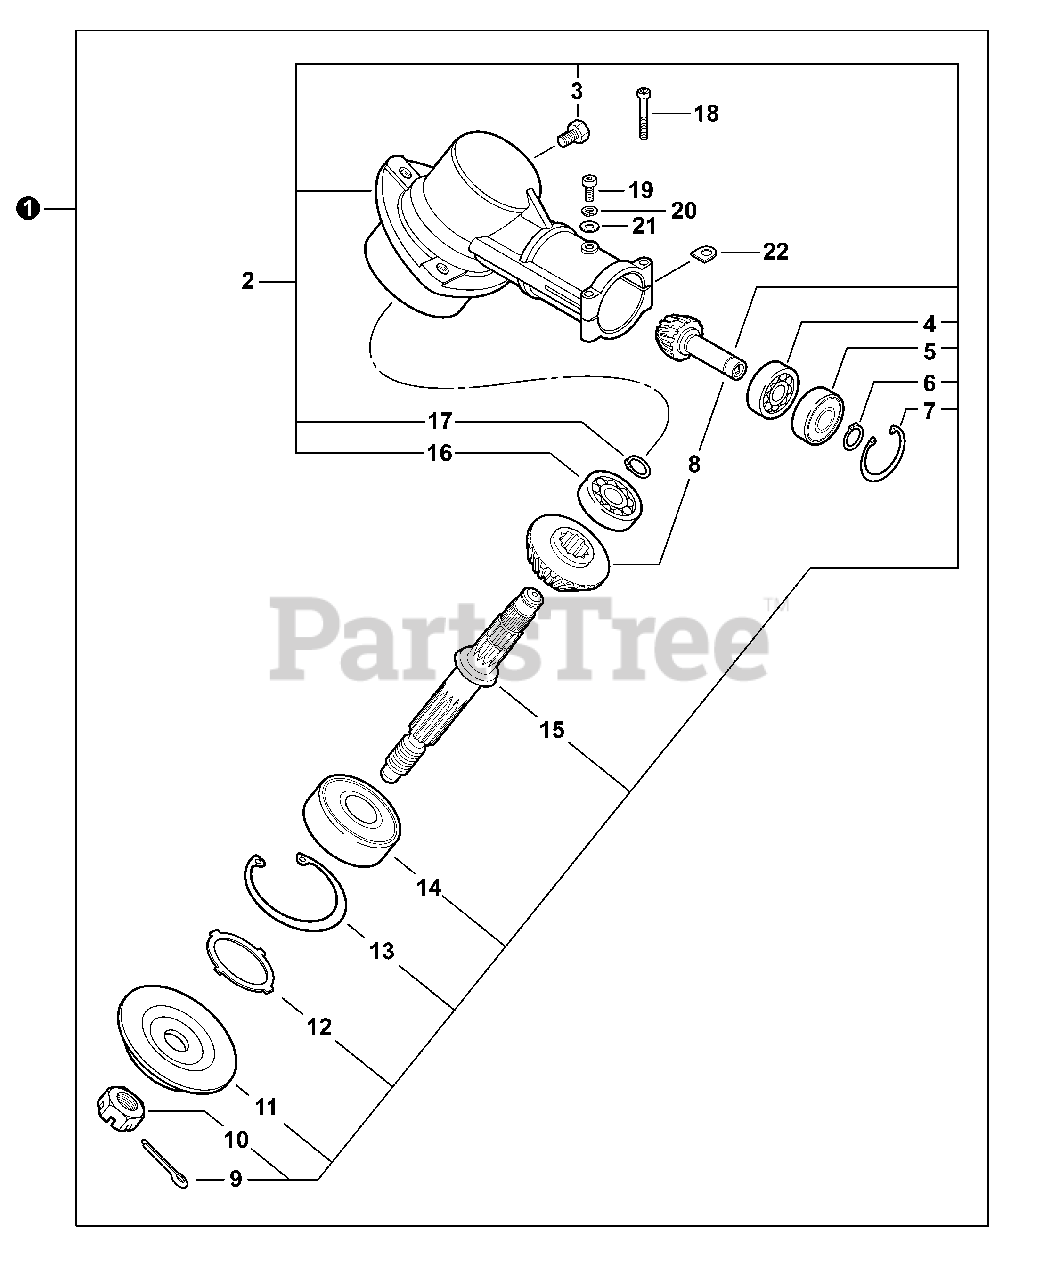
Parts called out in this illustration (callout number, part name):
1	GEAR CASE ASSY
2	BOLT M8×8
3	BEARING, BALL 609
4	RING, SNAP Ø12
5	SHAFT, GEAR
6	BEARING, BALL 6201
8	RING, SNAP Ø32
9	PLATE, ADAPTOR - UPPER
10	PLATE, ADAPTOR - LOWER
11	NUT 10×1.25 LH
12	PIN, COTTER 2×22
13	RING, SNAP Ø22
14	RING, SNAP Ø10
15	BEARING, BALL 6900Z
16	BEARING, BALL 6900
17	GEAR SET
19	BOLT, TORX 5×25
20	WASHER, FLAT 5.5×10×0.8
21	WASHER, SPRING 5
22	BOLT, TORX 5×12
